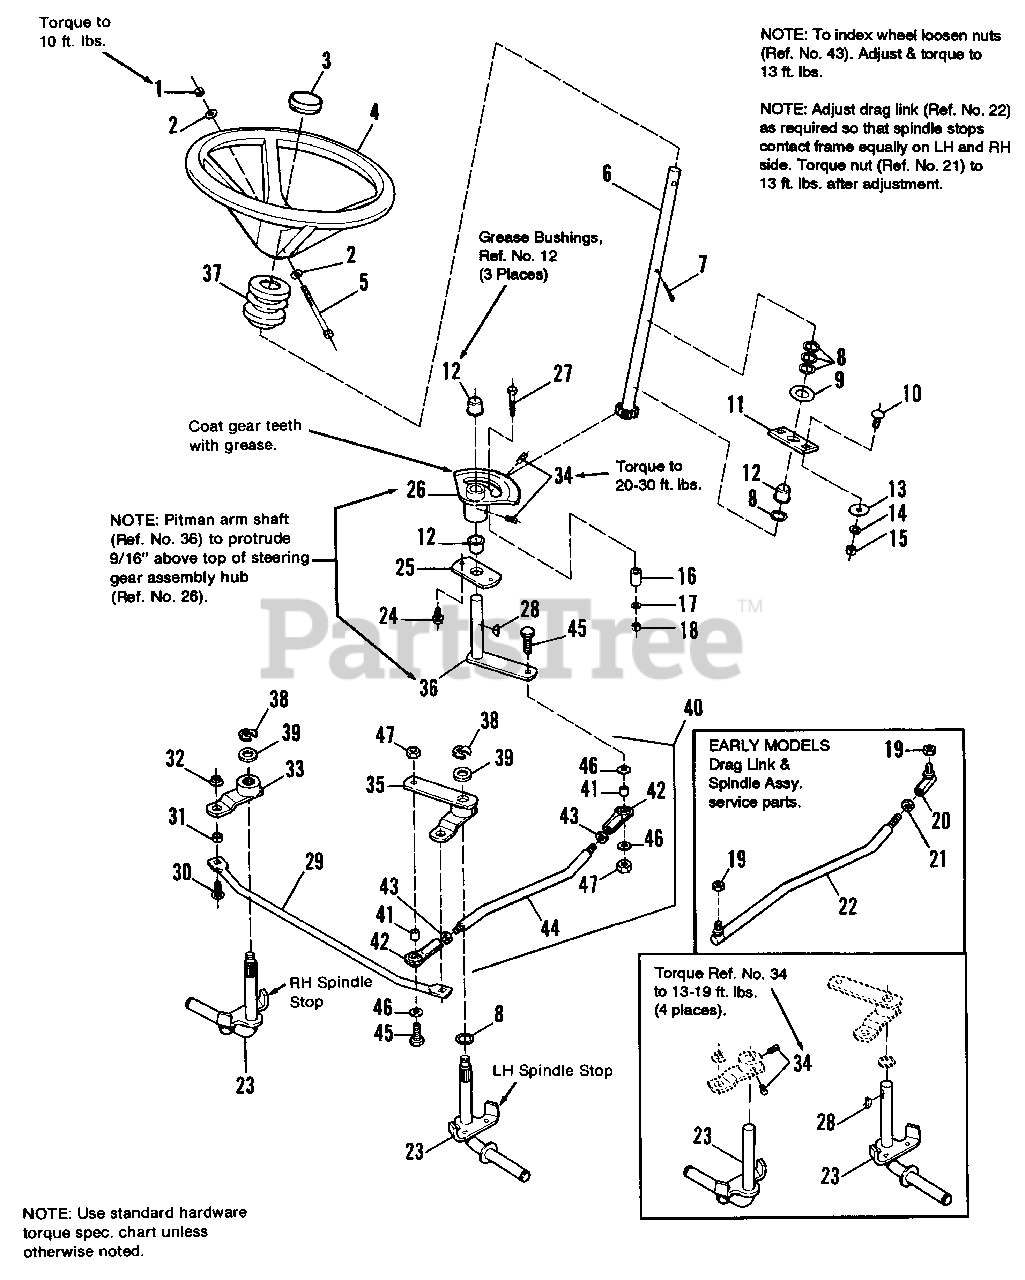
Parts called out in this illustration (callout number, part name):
1	NUT, Hex Lock, 5/16-18
2	WASHER, Steering Wheel
3	CAP, Steering Wheel
4	WHEEL, Steering
5	CAPSCREW, 5/16-18 x 3-1/2
6	* SHAFT ASSY., Steering
6	** SHAFT ASSY., Steering
8	WASHER, Plain, 49/64"
9	WASHER, Plain
10	CARRIAGE BOLT, 3/8-16 x 1
11	PLATE, Mounting, Steering
12	BUSHING, Nylon
13	WASHER, Plain, 13/32
14	LOCKWASHER, 3/8
15	NUT, Hex, Full, 3/8-16
16	SPACER, Stop
17	LOCKWASHER, 5/16
18	NUT, Hex, Full, 5/16-18
19	NUT, Special, 3/8-24
20	BALL JOINT (Round)
21	NUT, Jam, 3/8-24
22	DRAG LINK (Can be replaced by item #40)
23	* SPINDLE ASSY.
23	** SPINDLE ASSY.
24	SCREW, Taptite, 5/16-18 x 3/4
25	SECTOR MOUNTING PLATE
26	GEAR ASSY., Steering
27	CAPSCREW, Hex, 5/16-18 x 1-1/2
28	* KEY, Hi Pro (Qty. of 3 on Early Models. See inset page 4.)
30	CARRIAGE BOLT, 3/8-16 x 1
32	NUT, Hex Lock, Flange, 3/8-16
33	* ARM ASSY., Steering, R.H.
34	* SETSCREW, Sq. Hd., 5/16-18 x 1/2 (Qty. of 6 on Early Models. See inset page 4.)
35	* STEERING ARM ASSY., L.H.
35	** STEERING ARM ASSY., L.H.
36	PITMAN ARM ASSY.
37	** TUBE, Steering
38	** KLIP-RING, 5/8
40	DRAG LINK ASSY. (Includes Ref. Nos. 41-47)
42	BALL JOINT (Flat)
43	NUT, Hex, Jam, 1/2-20
45	CAPSCREW, Hex Head, 3/8-16 x 1-3/4
46	WASHER
47	** ARM ASSY., Steering, R.H.
47	NUT, Lock, 3/8-16
